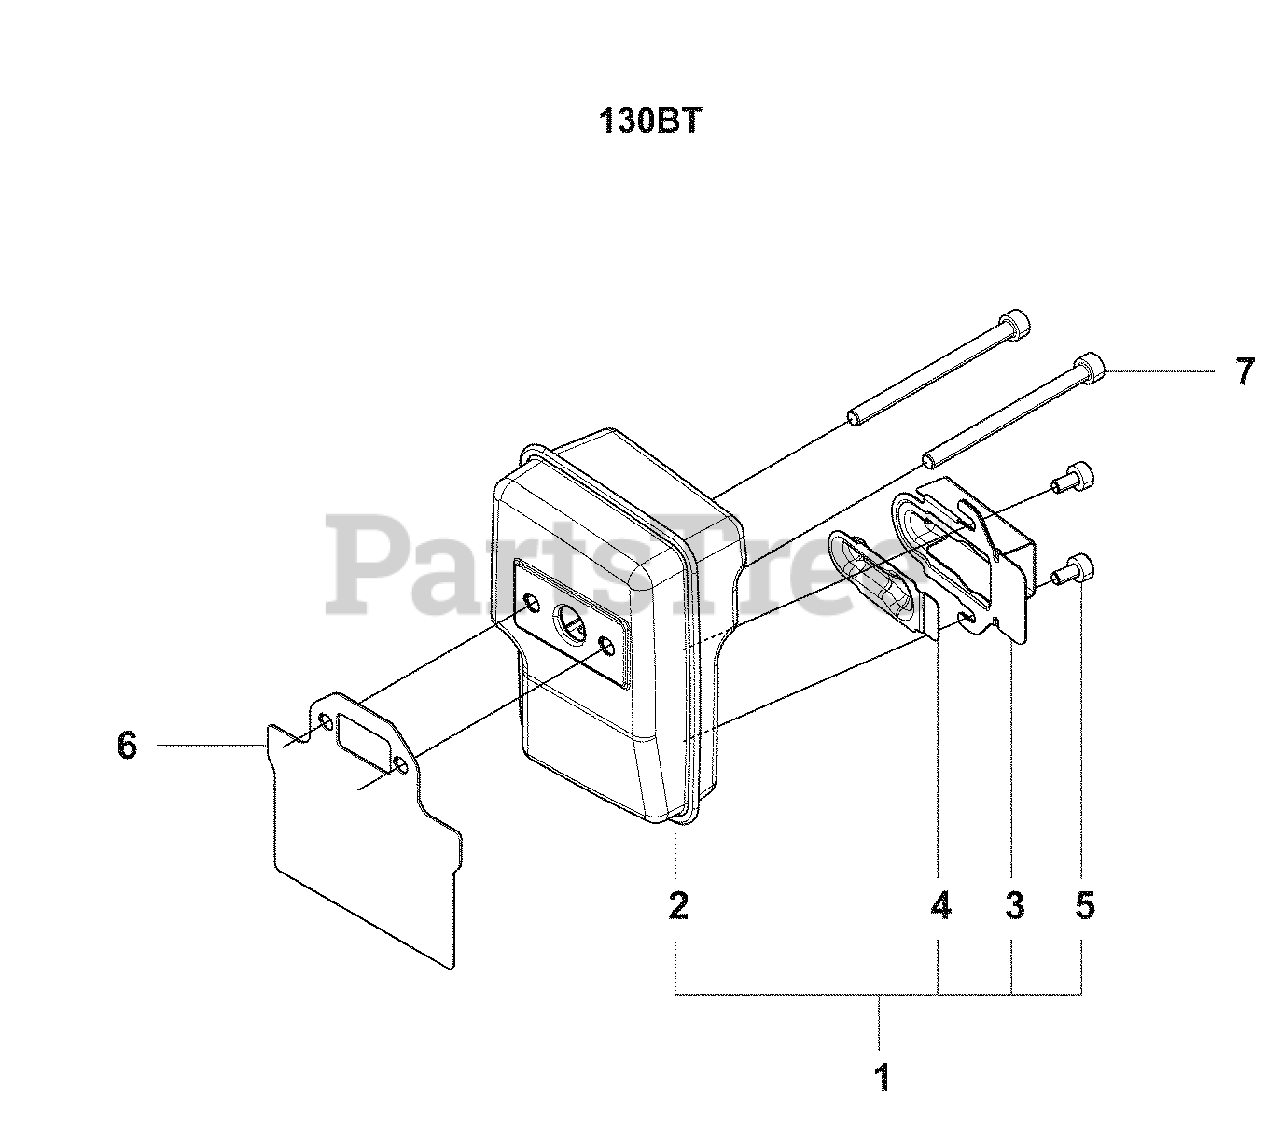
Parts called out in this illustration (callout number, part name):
1	Muffler, A
3	Exhaust Duct
7	Bolt
